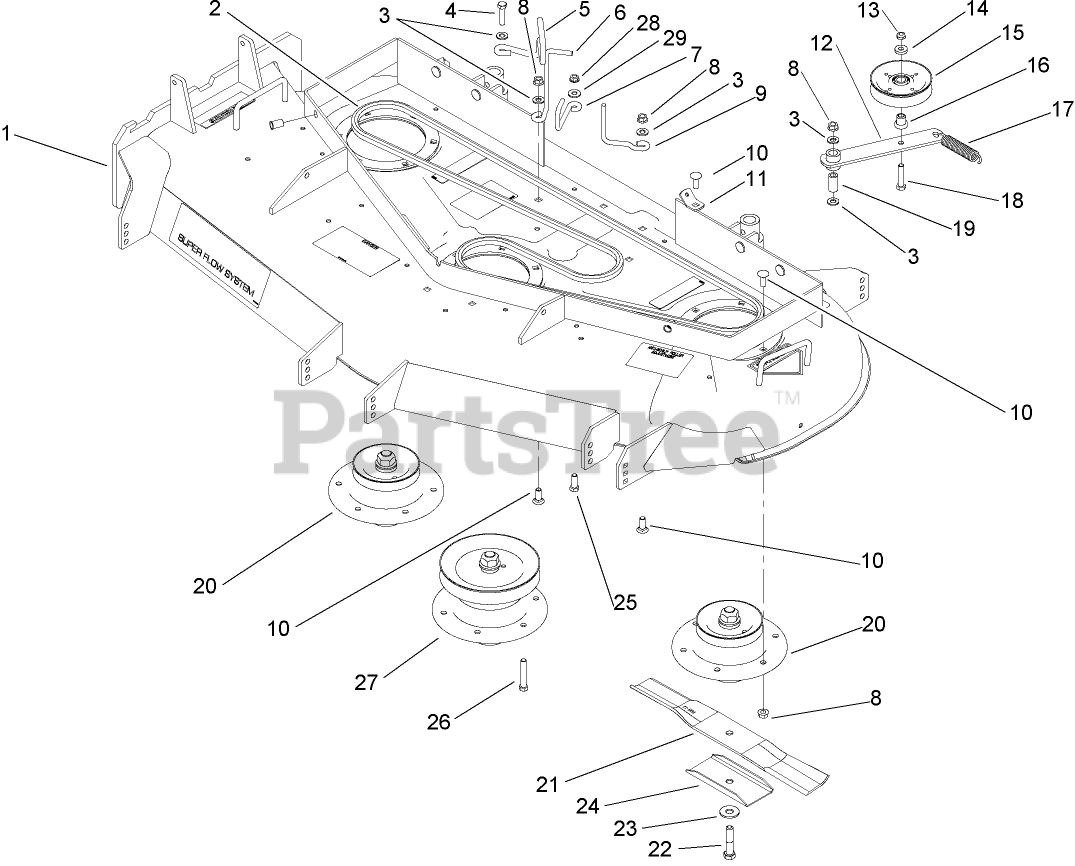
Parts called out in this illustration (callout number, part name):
1	DECK ASM
2	V-BELT
3	WASHER-FLAT
4	SCREW-HH
5	GUIDE-BELT
6	GUIDE-BELT
7	GUIDE-BELT
8	NUT-HF
9	ROD-BELT
10	SCREW-CARR
11	PLATE-SPRING
12	IDLER ARM ASM
13	NUT-HEX
14	WASHER-FLAT
15	PULLEY-IDLER
16	BUSHING-PULLEY
17	SPRING-EXTENSION
18	SCREW-HH
19	SLEEVE
20	SPINDLE HOUSING ASM
21	Blade
22	SCREW-BLADE
23	WASHER-FLAT
24	STIFFENER-BLADE
25	SCREW-HH
26	SCREW-HH
27	SPINDLE HOUSING ASM
28	NUT-HF
29	WASHER-FLAT
